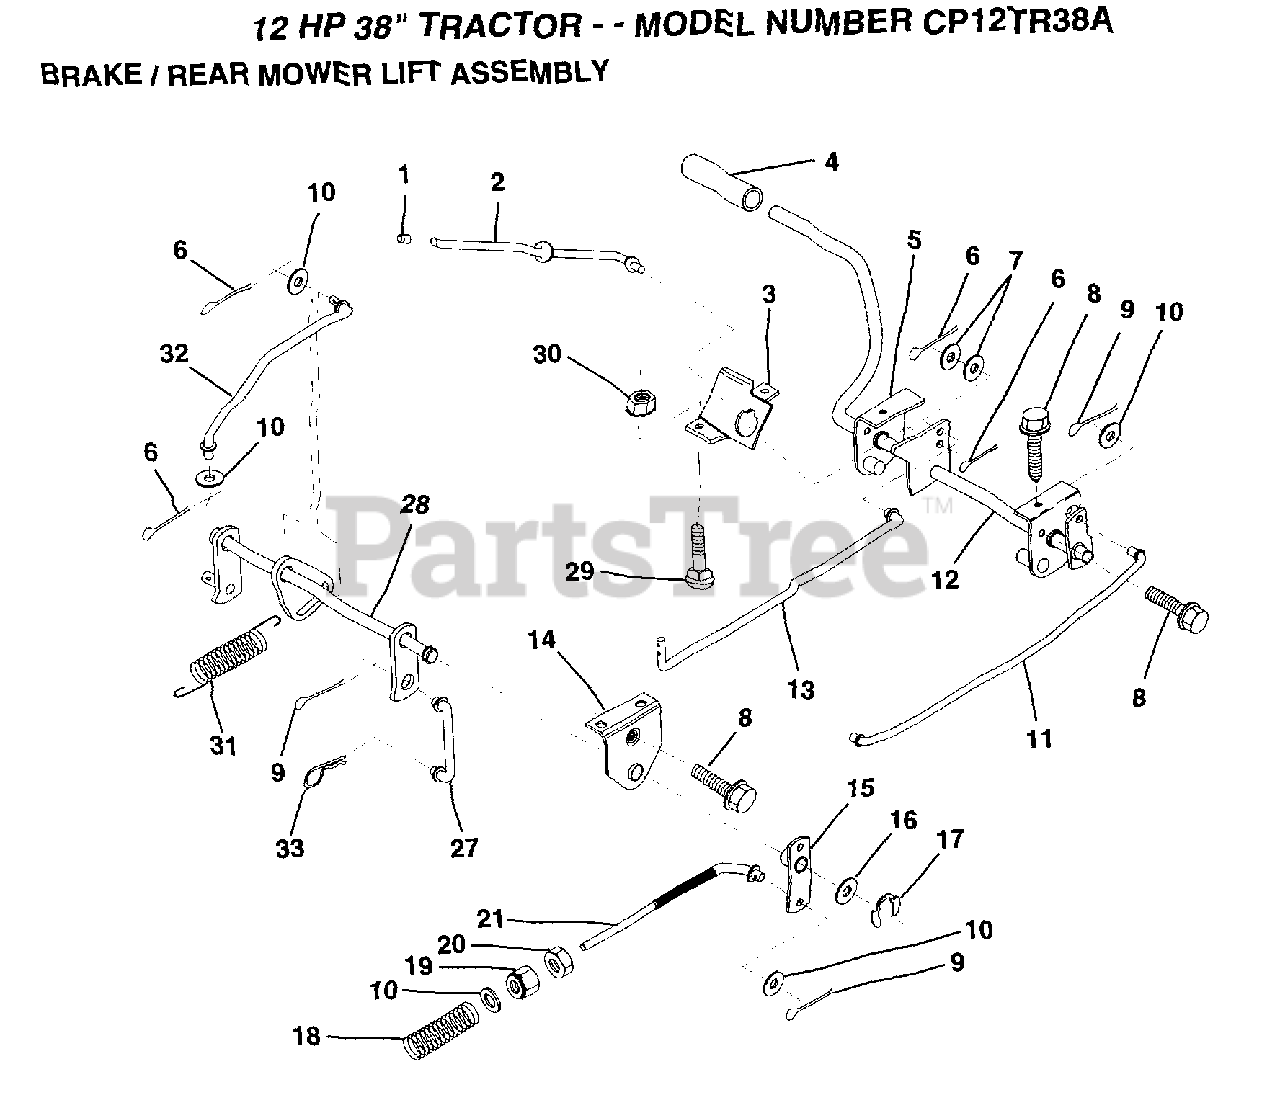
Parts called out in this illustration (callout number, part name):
1	PLUNGER CAP T
2	"ROD,PARK BRAKE"
3	"BRKT,PARK BRAKE"
4	PEDAL COVER T
5	BRK ASM CLUT LH
7	WASHER
8	SCREW LT
9	COTTER PIN
10	WASHER
11	"ROD,FRT BRAKE"
12	PEDAL ASM CLU/BRK
13	"ROD,CLUTCH"
14	"BRKT,LIFT SHAFT"
15	PVT BRAKE ARM ASM
16	WASHER T
17	KLIP RING
18	SPRING ROD LT
19	NUT
20	NUT
27	LINK LIFT REAR LR
28	LIFT.ASM.REAR.LR
31	COUNTER SPRING
32	LINK LIFT LEVER
